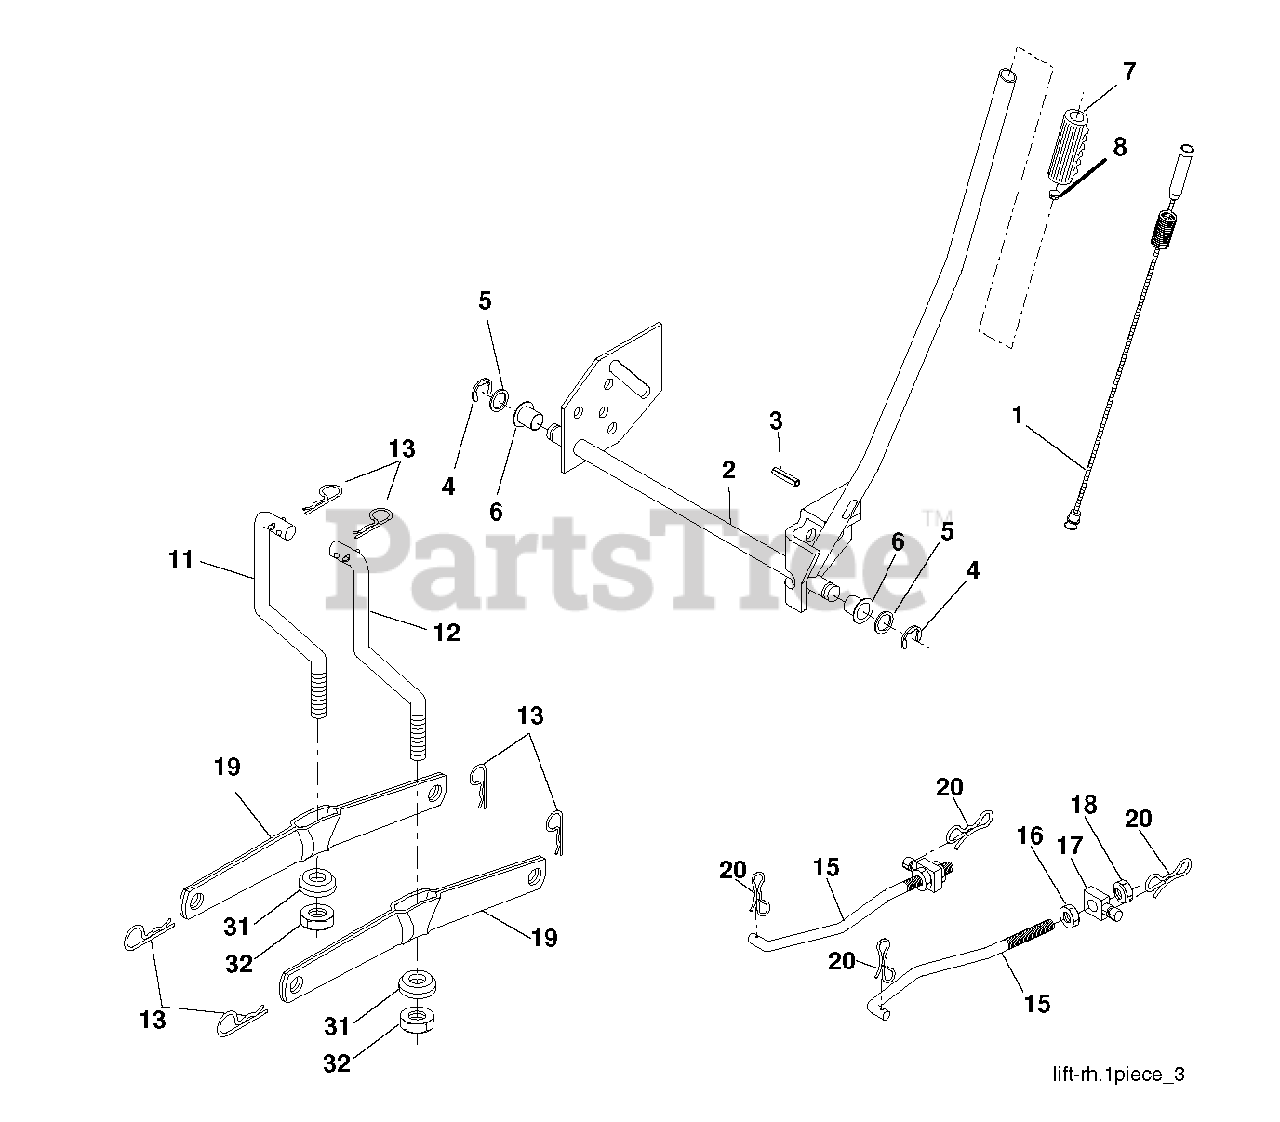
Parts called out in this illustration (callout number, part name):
1	PLUNGER.ASM.LIFT.LVR.BLK.17.32
2	SHAFT ASM R HANDLE
4	RETAINING RING LT
6	BEARING.NYLON
7	GRIP
8	PLUNGER BUT KIT
11	LINK LIFT LH
12	LINK LIFT RH
13	RETAINER-SPRNG RB
15	LINK.SUSPENSION.FRONT
16	NUT
18	NUT
19	ARM.REAR.SUSPENSION
20	PIN.COTTER.7/16.BOW TI
31	BEARING.PIVOT.LIFT
32	NUT CROWNLOCK 3/8-24
